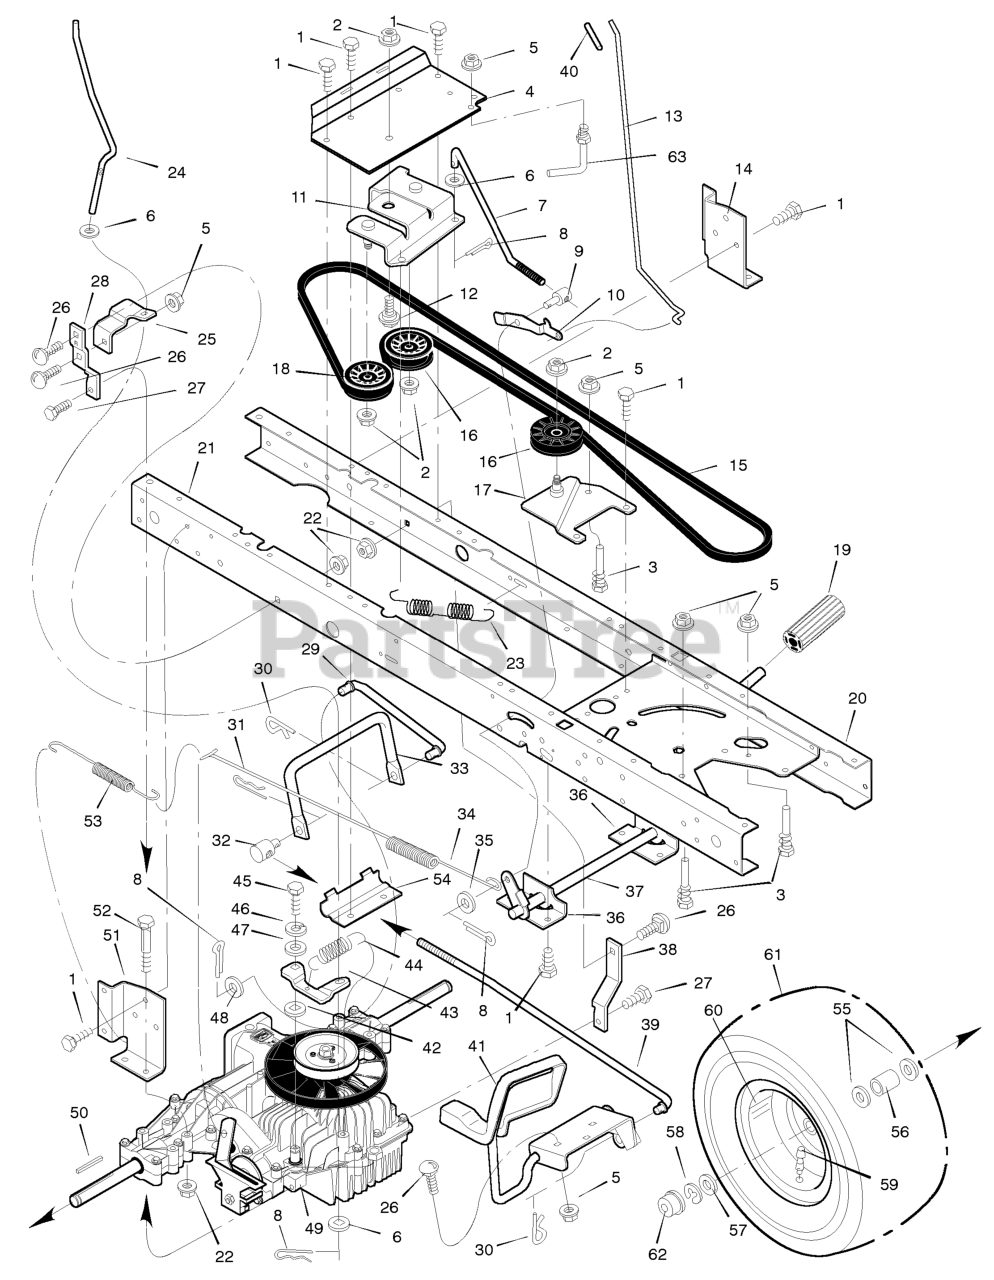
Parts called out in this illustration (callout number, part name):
2	Nut, Flange
3	Guide, Belt
4	Bracket, Idler
5	Locknut
6	Washer
7	Rod, Clutch
8	Pin, Cotter
9	Adjuster
10	Latch, Parking Brake
11	Bracket Assembly, Idler
12	Bolt, Shoulder
13	Rod, Parking Brake
14	Bracket, Transaxle
16	Pulley, Idler
17	Arm Assembly, Idler
18	Pulley, Idler
19	Pedal
20	Frame, Left
21	Frame, Right
22	Nut, Flange
23	Spring, Extension
24	Rod, Disconnect
25	Bracket, Disconnect
26	Bolt, Carriage
28	Strap, Right Torque
29	Rod, Link
30	Pin, Hair
31	Pin, Hair
32	NUT, Adjusting, 1/2-13
33	Rod, Yoke
34	Spring, Extension
35	Washer
36	Bracket, Pivot
37	Lever, Clutch/Brake
38	BRACKET, Torque Strap, LH
39	Rod, Link
41	Pedal, Speed Control
43	Arm, Disconnect
44	Spring
46	Lockwasher
48	Washer
49	Transaxle **
50	Key, Square
51	Bracket, Right Transaxle
52	Bolt
53	Spring, Extension
54	Clamp, Transaxle
58	E- Ring
59	Valve Stem
60	Wheel & Tire Assembly
61	Tire *
62	Cap, Hub
63	Guide, Belt
